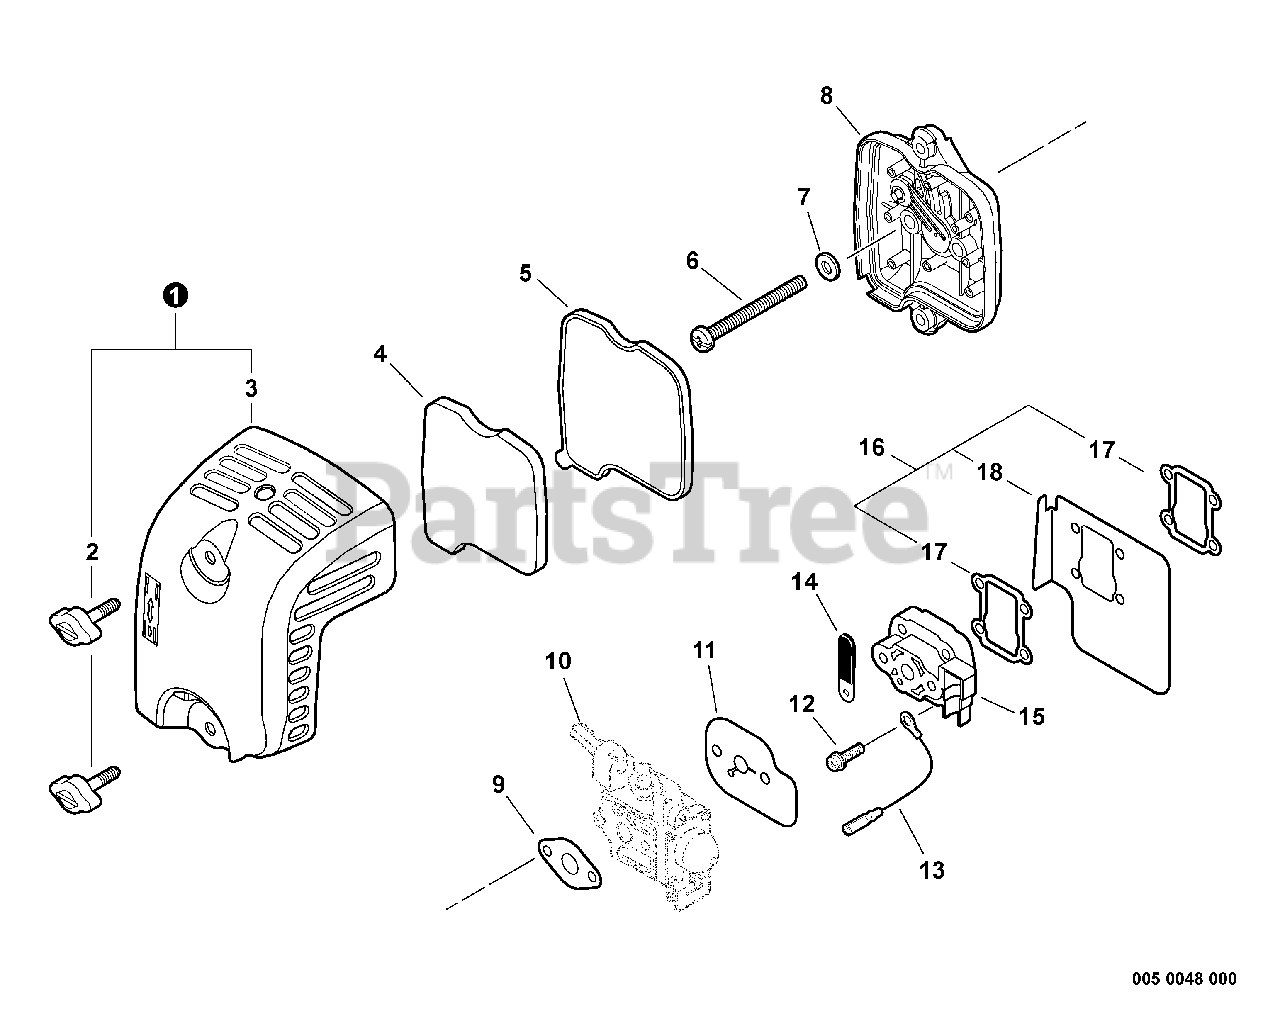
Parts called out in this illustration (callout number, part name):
1	AIR FILTER COVER ASSY
2	THUMBSCREW
3	COVER, AIR FILTER
4	PRE-FILTER -- FOAM
5	FILTER, AIR
6	SCREW - 5X60
7	WASHER - 5
8	CASE, AIR FILTER
9	GASKET, INTAKE
10	CARBURETOR
11	GASKET, INTAKE
12	SCREW - 5X22
13	LEAD - GROUND
15	INSULATOR ASSY
16	INTAKE SHIELD ASSY
17	GASKET, INTAKE
18	SHIELD, INTAKE
